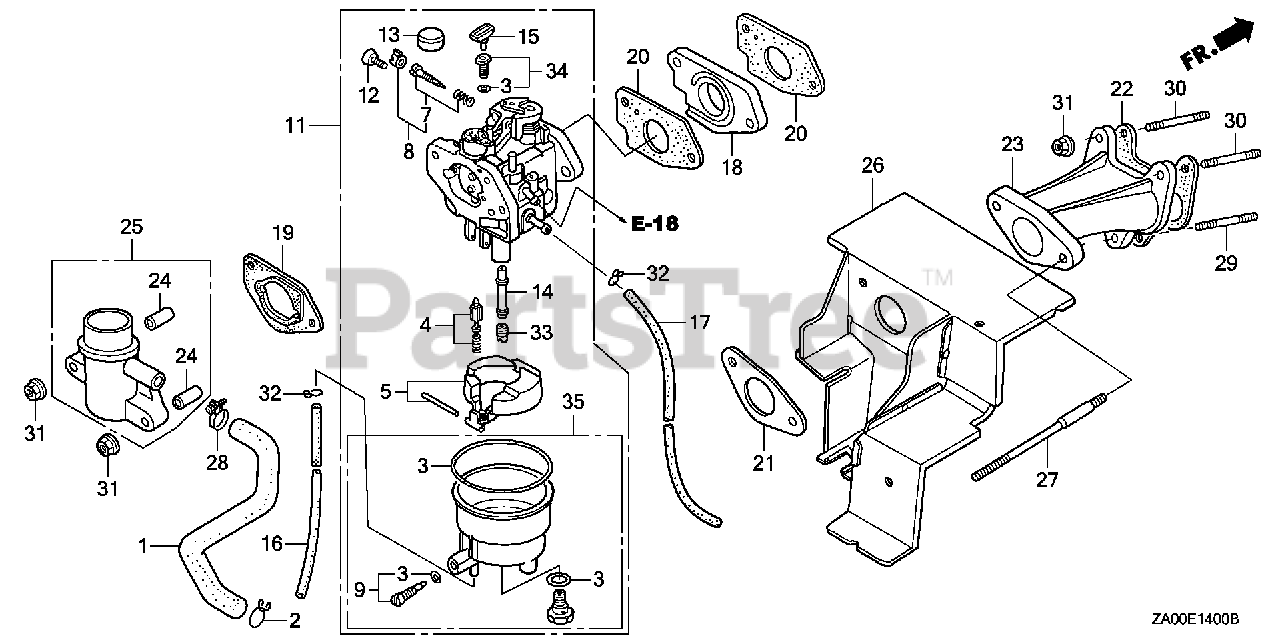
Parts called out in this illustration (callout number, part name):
1	TUBE, BREATHER
2	CLIP, BREATHER TUBE
3	GASKET SET
4	VALVE SET, FLOAT
5	FLOAT SET
6	CHAMBER SET, FLOAT
7	SCREW SET, PILOT (Honda Code 1441500). (CARBURETOR NO.)
8	SCREW SET (Honda Code 4219879). (CARBURETOR NO.)
9	SCREW SET, DRAIN (ADVENTURE GREEN) (CARBURETOR NO.)
10	BOLT KIT, FUEL CHAMBER
10	SCREW SET
11	CARBURETOR ASSY. (BE27B E)
12	SCREW, THROTTLE STOP
13	CAP, CHOKE LEVER DUST
14	NOZZLE, MAIN
16	TUBE, FUEL DRAIN
17	TUBE, AIR VENT
18	INSULATOR, CARBURETOR
19	SPACER, CARBURETOR
20	GASKET, CARBURETOR
21	GASKET, INSULATOR
22	GASKET, IN. MANIFOLD
23	MANIFOLD, IN.
24	COLLAR, AIR CLEANER Use from Engine SN 1786085.
25	ELBOW, AIR CLEANER
26	COVER, EX.
27	BOLT, STUD (8X123)
28	CLIP A18, TUBE
29	BOLT, STUD (6X32)
29	BOLT 2, STUD (6X20)
30	BOLT, STUD (6X22)
30	BOLT, STUD (6X28)
31	NUT, FLANGE (6MM)
32	CLIP, TUBE (B8)
33	JET, MAIN (#82)
33	JET, MAIN (#85) Use up to Engine SN BE81B B.
33	JET, MAIN (#88) Use up to Engine SN BE81B B.
34	JET SET, PILOT (#45)
35	BOLT KIT, FUEL CHAMBER
